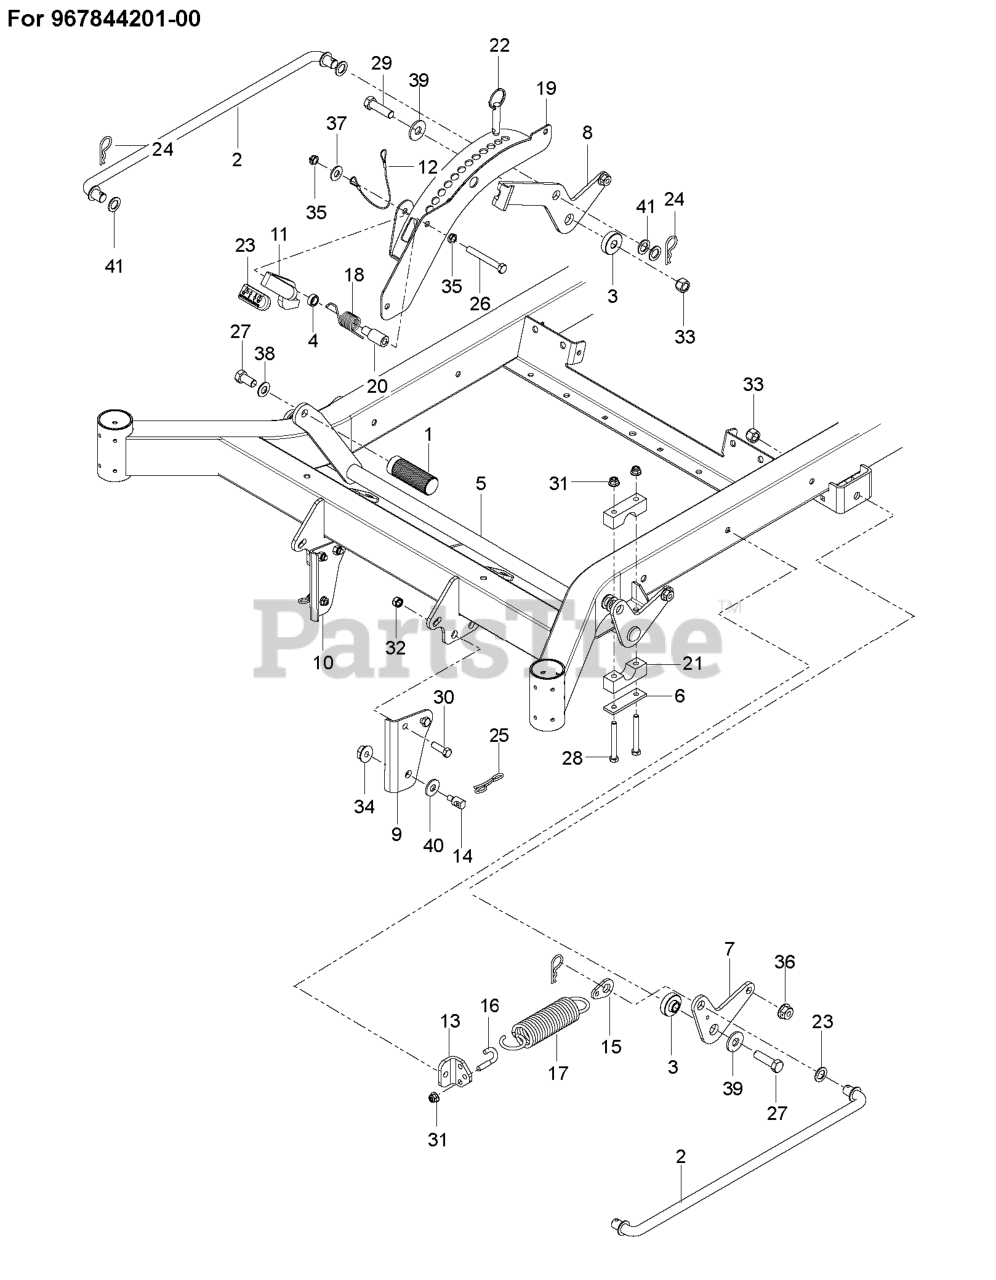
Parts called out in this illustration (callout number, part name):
1	PEDAL, DECK HEIGHT
2	CROSS LINK
3	SPACER.IDLER.METAL.POWDER
4	SPACER, .3
5	LIFT.PNT.MZ.DECK.WELD.E-DIP
6	REINFORCEMENT.PLATEX431
7	BELLCRANK, RR, LIFT
8	BELLCRANK, RR, RT
9	BRACKET.PNT.SUSP.CHAS.FR.LH.OR
10	BRACKET.PNT.SUSP.CHAS.FR.RH.OR
11	LATCH, TRANSPORT
13	MOUNT, SPRING
14	STUD.FASTNER.W/ANTI-ROTATE
15	TAB, SPRING
18	SPRING, TORSION
19	HEIGHT, ADJUST, DECK
20	PIVOT, LATCH, TRANSPORT
21	PILLOW BLOCK
22	PIN, 1/2 X 1 1/2, DETENT RING
23	GRIP, TRANSPORT-RELEASE
24	PIN, COTTER 1 3/4
25	PIN.COTTER.7/16.BOW TI.
26	BOLT.HEX.FIN.3/8-16 X 3.GR5
27	HHCS 1/2-13 X 1
29	HCS 1/2-13 X 1 3/4 GR 8
30	HCS 3/8-16X1.GRD.5.ZD
31	5/16-18 NYLOC FLANGE NUT
32	NUT 3/8-16 NYLOC
33	NUT.LK.W/WSH.1/2.
34	NUT LOCK HEX FLANGE 5/16-18
35	NUT HEX 3/8-16 NYLON, THIN
36	NUT LOCK FLG 3/8-16 UNC
37	RP WASHER 3/8 FLAT
38	CONTACT BELLSPR 1/2
39	WASH USS FLAT 1/2
40	WASHER.CLEAR.ZINC
